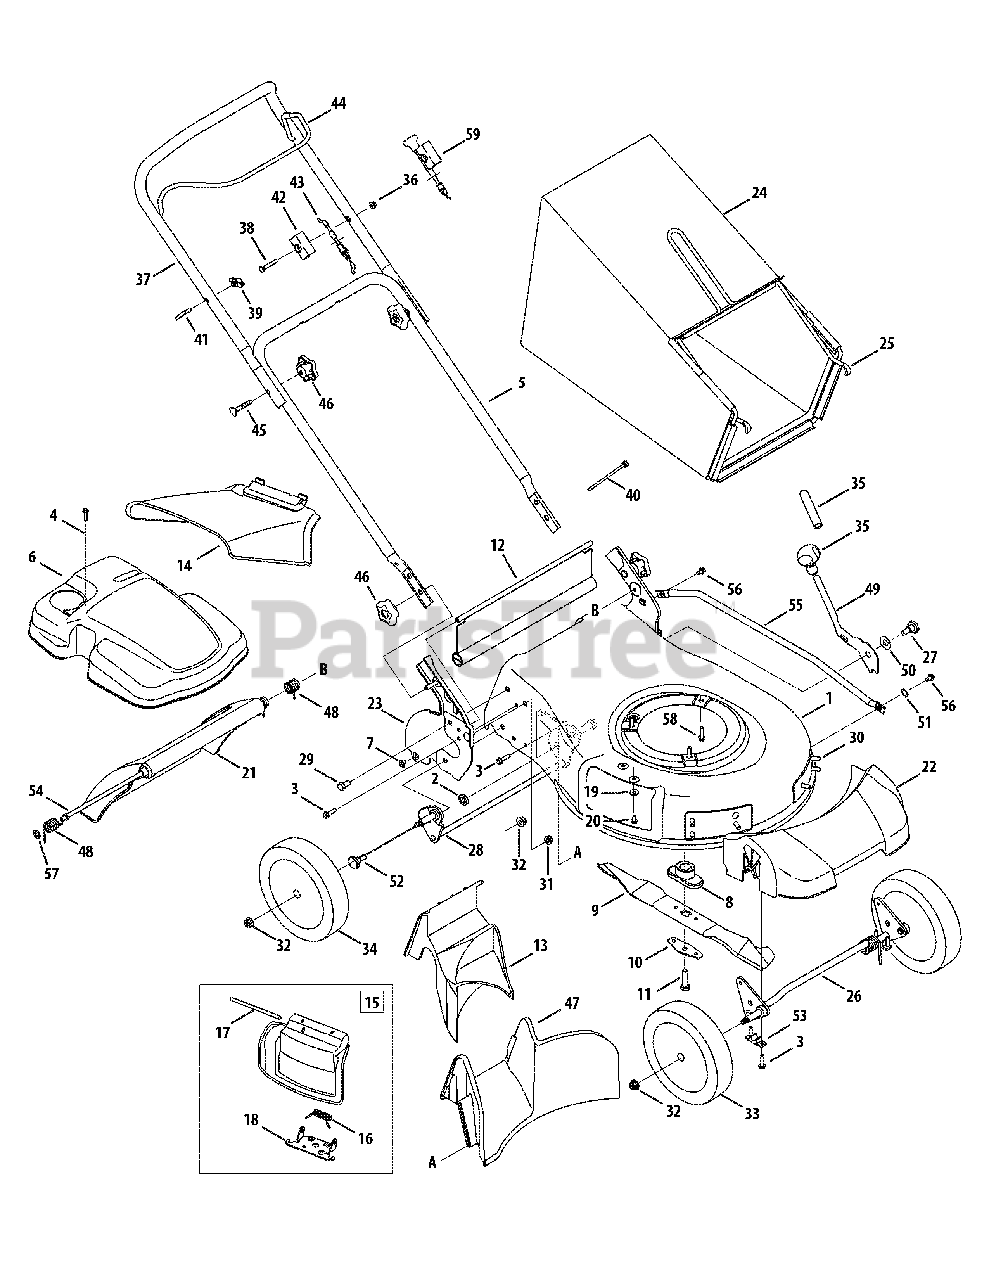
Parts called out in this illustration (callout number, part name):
2	Spacer, .515 x 1.00 x .310 Lg.
3	Screw, 1/4-15 x 1.000
4	Screw, HL, #12-16 x 1.00
5	Lower Handle
6	Engine Shroud - Choke
7	Screw, #10-16 x .500
8	Blade Adapter
9	Mulching Blade
10	Blade Bell Support
11	Screw, 3/8-24 x 1.50
12	Trailing Shield
13	Rear Mulch Plug
14	Side Discharge Chute
15	Mulch Plug (Incl. 16-18)
16	Torsion Spring
17	Hinge Pin
18	Chute Deflector Adapter
19	Beleville Washer
20	Screw
21	Rear Door
22	Front Cover
23	Handle Bracket - RH
23	Handle Bracket - LH
24	Grass Bag
25	Grass Bag Frame
26	Front Bracket Assembly
27	Screw, Shoulder, .50 x .66
28	Rear Bracket Assembly
29	Hhcs, 5/16-18 x .625
30	Screw, 5/16-14 x .750
31	Nut, Flange Lock, 5/16-18
32	Nut, Flange Lock, 3/8-16
33	Front Wheel
34	Rear Wheel
36	Nut, Flange Lock, 1/4-20
37	Upper Handle
38	Screw, 1/4-20 x 1.50
40	Cable Tie
41	Rope Guide
42	Control Cable Mount
43	Control Cable
44	Blade Control
45	Bolt Carriage, 5/16-18 x 2.0
46	Star Knob
47	Rear Baffle
48	Door Torsion Spring - RH
48	Door Torsion Spring - LH
49	Spring Lever
50	Washer, Bell, .510 x 1.14 x .040
51	Washer, Wave, .385 x .598
52	Screw, Shoulder, .500 Dia. X .434
53	Bushing, Lock, .505 Dia. X .62
54	Rear Door Pivot Rod
55	Cross Bracket
56	Screw, 1/4-20 x .50
57	Nut, Spd.
58	Screw, tt, 3/8-16 x 1.00
59	Choke Cable
